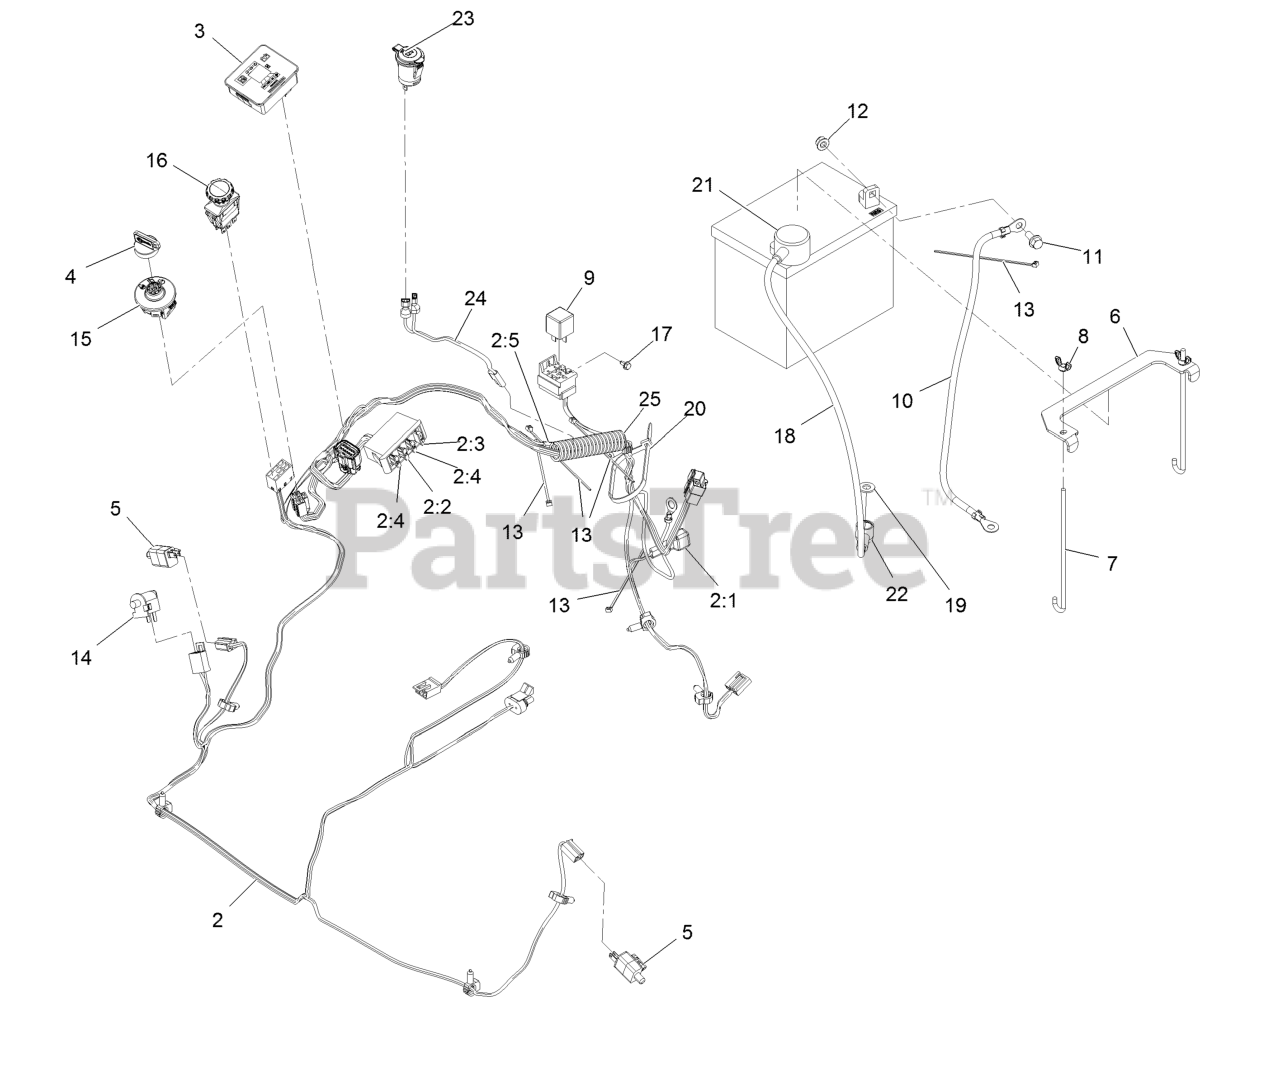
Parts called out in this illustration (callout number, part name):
2	Harness-Wire, Main
2:2	Fuse-Blade, 10 Amp
2:3	Fuse-Blade, 15 Amp
2:4	Fuse-Blade, 25 Amp
2:5	Cap-Plug
3	Fuel/Hour Meter ASM
4	Key-Ignition
4	Key-Exmark Logo
6	Strap-Tie Down, Battery
7	Bolt-Holddown
8	Wingnut-Nyloc 1/4-20
9	Relay-12Vdc 40 Amp
10	Cable-Battery, Negative
11	Screw-HH Flg 5/16-18 X 3/4
12	Nut-Nyloc 5/16-18 Flg
13	Tie-Cable 5 1/2 (Small)
15	Switch-Ignition
16	Switch-PTO, 10 Amp
17	Screw-HWH #10-24 X 3/8
18	Cable-Battery, Positive
19	Washer-3/8 SAE
20	Tie-Cable 7 15/16 (Large)
21	Insulator-Battery
22	Insulator-Solenoid
23	Port-Power, 12V
24	Harness, Receptacle 12V
25	Cover-Hose
